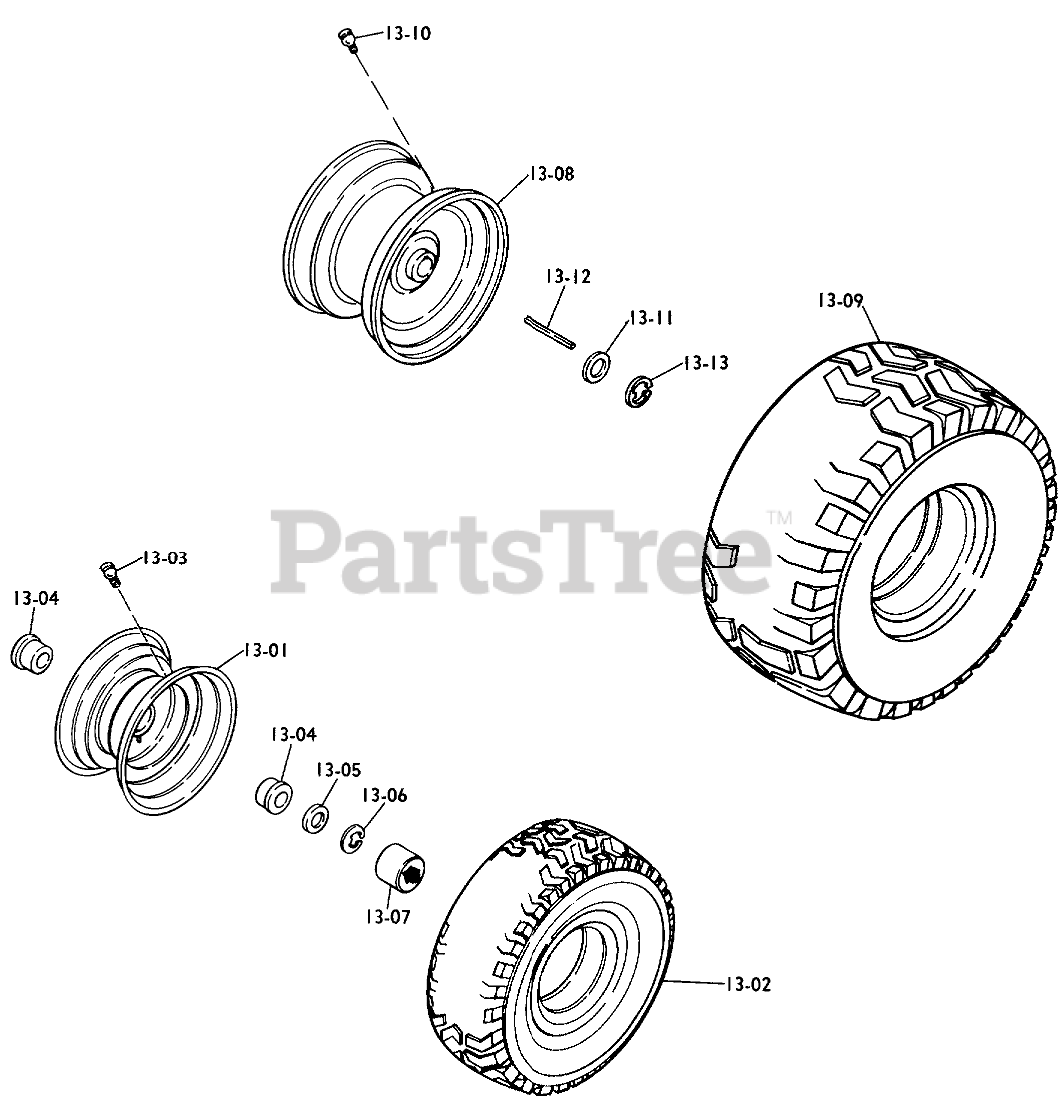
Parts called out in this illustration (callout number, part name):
13-01	Front Wheel
13-03	VALVE
13-04	Bearing
13-05	WASHER
13-06	E-RING
13-07	HUB CAP
13-08	Rear Wheel
13-10	VALVE
13-11	WASHER
13-12	SQ KEY
13-13	Snap Ring
